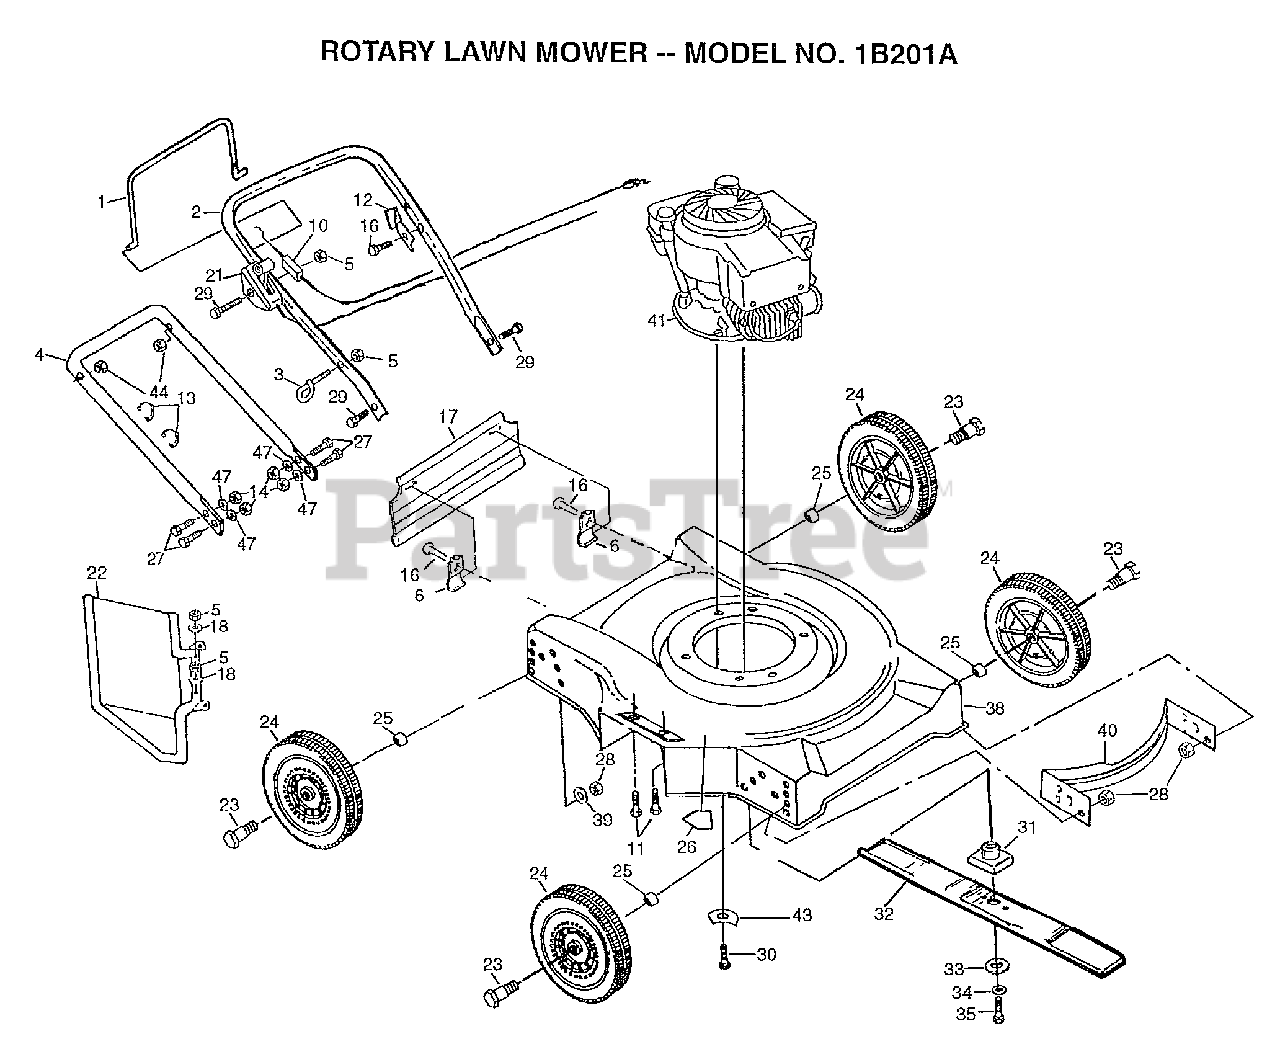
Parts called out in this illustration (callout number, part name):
1	CONTROL BAR PM
2	UPPER HANDLE
3	ROPE GUIDE
4	HANDLE LWR PM
6	"BRKT,DEFL PM"
10	CABLE.ZONE.CONTRO
11	BOLT LT
12	"BRKT,UPSTOP"
13	CABLE CLIP PM
14	LOCKNUT
16	TAPPING SCREW
17	SKIRT.REAR.20RD.
21	CONTROL.THL.49.35
22	"GRD,DISCHARGE"
23	AXLE BOLT
24	WHEEL ASSY
26	DECAL HYT
28	LOCKNUT PM
29	SCREW.HXHD.WASH.
30	BOLT.ENG.3/8-16
31	BLADE ADAPTOR
32	BLADE.20.MULCH.AY
33	"WASHER,HARDEN"
34	LOCKWASHER
35	SCREW
47	STEEL WASHER
